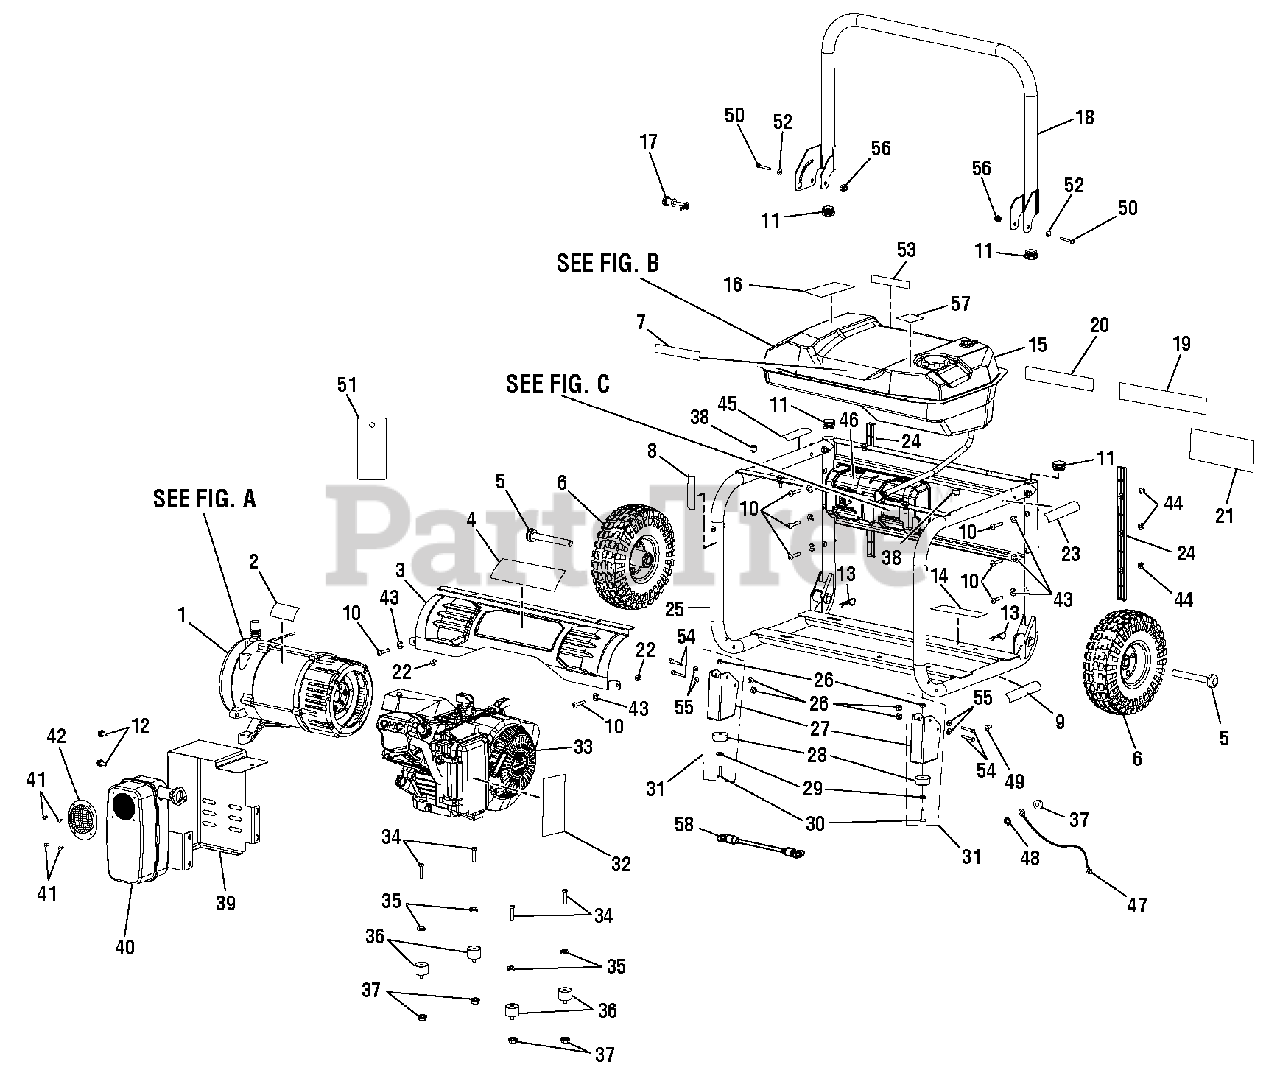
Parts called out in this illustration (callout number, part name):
1	Generator Head Assembly (See Figure A)
2	Data Label (PS905055S)
3	Back Panel Assembly
4	Back Panel Logo Label
7	Fire Distance Label
8	Hot Surface Label
9	Label (UL fire warning)
10	Bolt (1/4-20 x 42.5 mm, Torx Hd.)
12	Bolt (5/16-24 x 5/8 in.)
13	Hitch Pin
14	Lubricant Label
15	Fuel Tank Assembly
16	CPSC Label
17	Handle Release Pin Assembly
18	Handle Assembly
19	Danger Label
20	Ground Warning Label
21	Logo Label
22	Lock Nut (1/4-20)
23	Fire Danger Label
24	Frame Slide Rails
25	Frame Assembly
26	Lock Nut (1/4-20)
29	Washer (1/4 in.)
30	Bolt (1/4-20 x 1 in., Hex Hd.)
31	Foot Assembly
32	Starting Instruction Label
34	Bolt (5/16-18 x 1.5 in.)
35	Lock Washer (5/16)
36	Isolator (Generator)
37	Hex Nut (5/16-18, Flange)
38	Rubber Handle Bumper
39	Back Muffler Cover
40	Muffler (Subaru EX30)
41	Screw (8-32 x 3/8 in.)
42	Spark Arrestor
43	Lock Washer (M6)
44	Hex Nut (1/4-20)
45	Pin Release Label
46	Control Panel (See Figure C)
47	Ground Wire Assembly
48	Star Washer (5/16 in.)
49	Bolt (5/16-18 x 3/4 in.)
50	Bolt (M8 x 55 mm, Hex Hd.)
51	Danger Hang Tag
52	Washer (3/8 in.)
53	Mexico Support Label
54	Bolt (1/4-20 x 2 in., T30 Torx Hd.)
55	Washer (1/4 in.)
56	Hex Nut (M8)
57	E85 Label
58	Bond Wire
